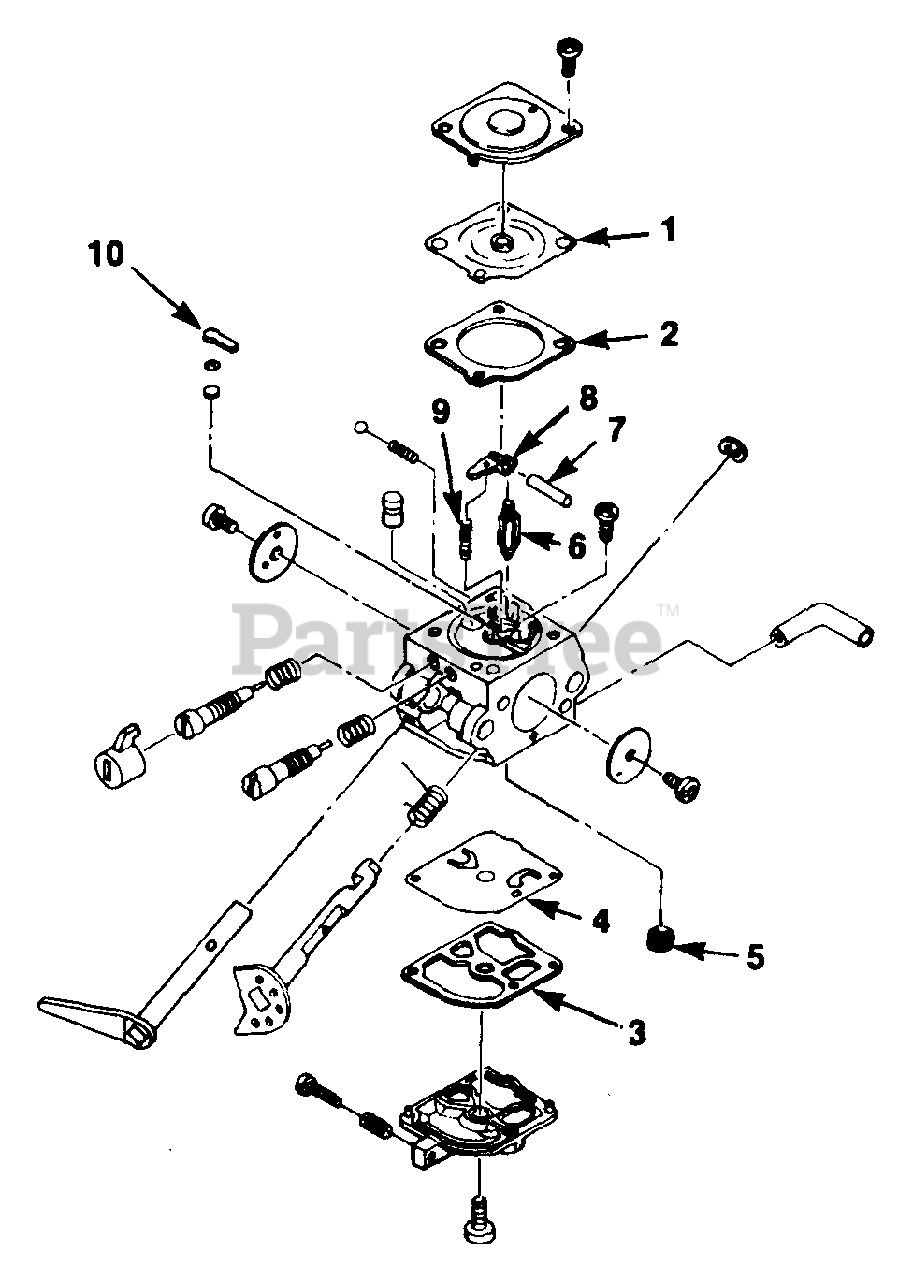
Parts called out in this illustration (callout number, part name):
1	Repair Kit
2	Gasket/Diaphragm Kit
2	Repair Kit
3	Gasket/Diaphragm Kit
3	Repair Kit
4	Gasket/Diaphragm Kit
4	Repair Kit
5	Repair Kit
6	Repair Kit
7	Repair Kit
8	Repair Kit
9	Repair Kit
10	Repair Kit
